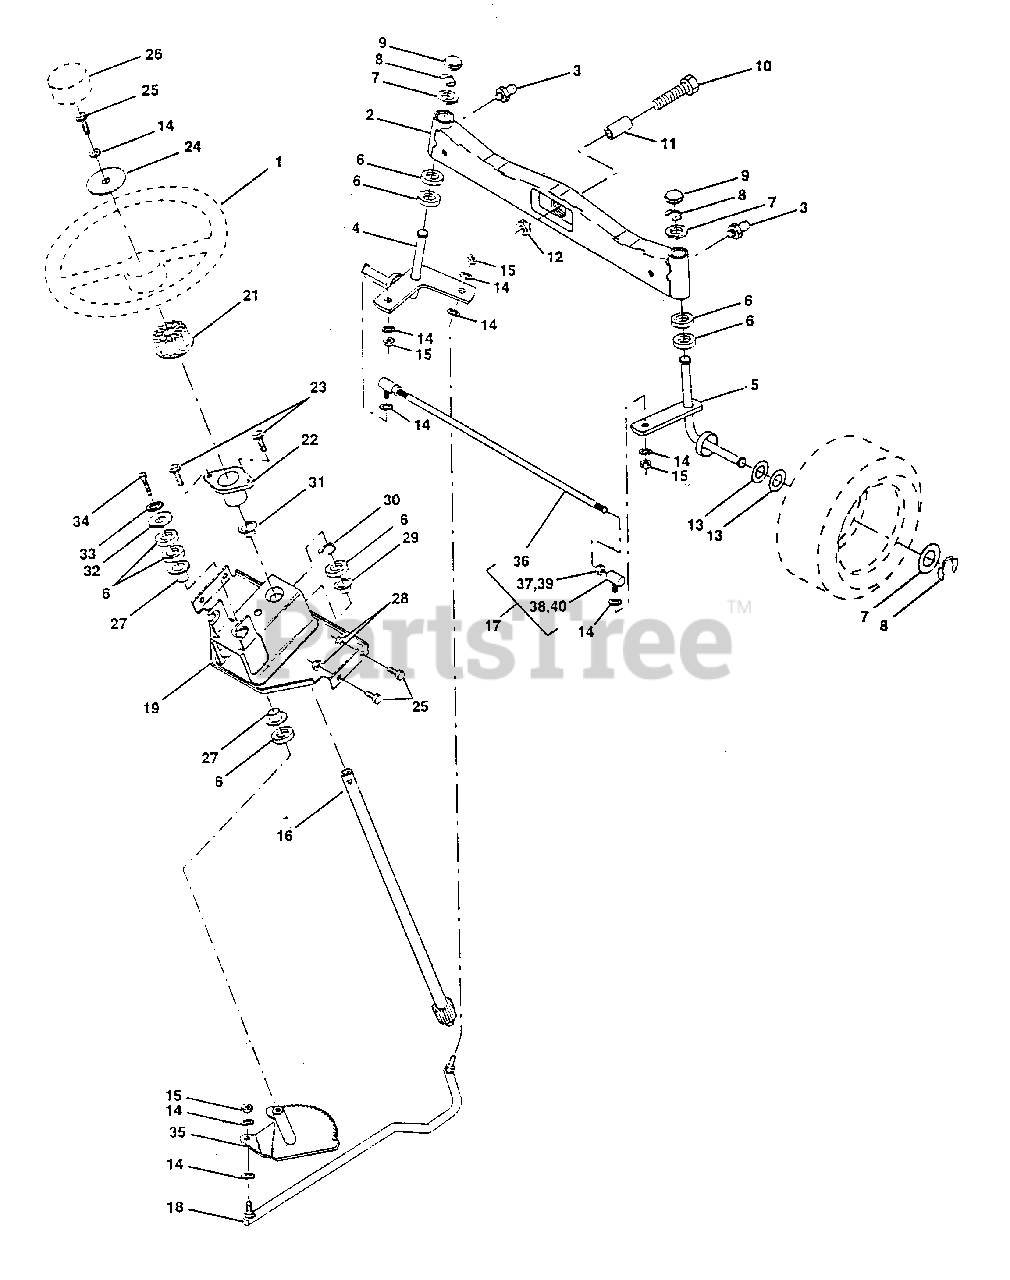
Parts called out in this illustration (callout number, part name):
1	Wheel, Steering
2	Axle Asm., Front
3	Fitting, Grease
4	Spindle Asm, LH
5	Spindle Asm., RH
6	Bearing, Race Thrust Harden
7	Washer 25/32 x 1-5/8 x 16 Ga.
8	Ring, Klip #T5304-75
10	Bolt, Fin Hex 5/8-11 x 2-3/4
11	Spacer, Brg. Axle Front
12	Nut, Lock Flange 5/8-11 Unc
13	Washer 25/32 x 1-1/4 x 16 Ga.
14	Washer, Lock Hvy Hlcl Spr 3/8
15	Nut, Fin Hex 3/8-24 Unf
16	Shaft Asm., Steering
17	Rod Asm., Tie Ball J Ball Vgt (Inc. Key No. 36-40)
18	Draglink, Ball Joint Solid Vgt
19	Support Asm., Steering Vgt
21	Adapter, Wheel Steering
22	Bushing, Strg. Blk
23	Screw, Slftp #10-16 x 1/2 Ty-b
24	Washer 13/32 x 2-3/8 x 8 Ga.
25	Bolt, Fin Hex 3/8-16 x 1 Gr.5
26	Cap, Wheel Steering
27	Bearing, Col. Strg.
28	Nut, Lock Hex W/Wsh 3/8-16 Unc
29	Bearing, Flange
30	Ring, Klip Truarc #5304-75
31	Bushing, Nyliner Snap
32	Washer 11/32 x 1 x 10 Ga.
33	Washer, Lock Hvy Hlcl Spr 5/16
34	Bolt, Hex Hd 5/16-18 x 3/4
35	Gear, Sector Steering
36	Tie Rod
37	Jam Nut RH Thread
38	Joint Asm. Ball RH Thread
39	Jam Nut LH Thread
40	Joint Asm. Ball LH Thread
